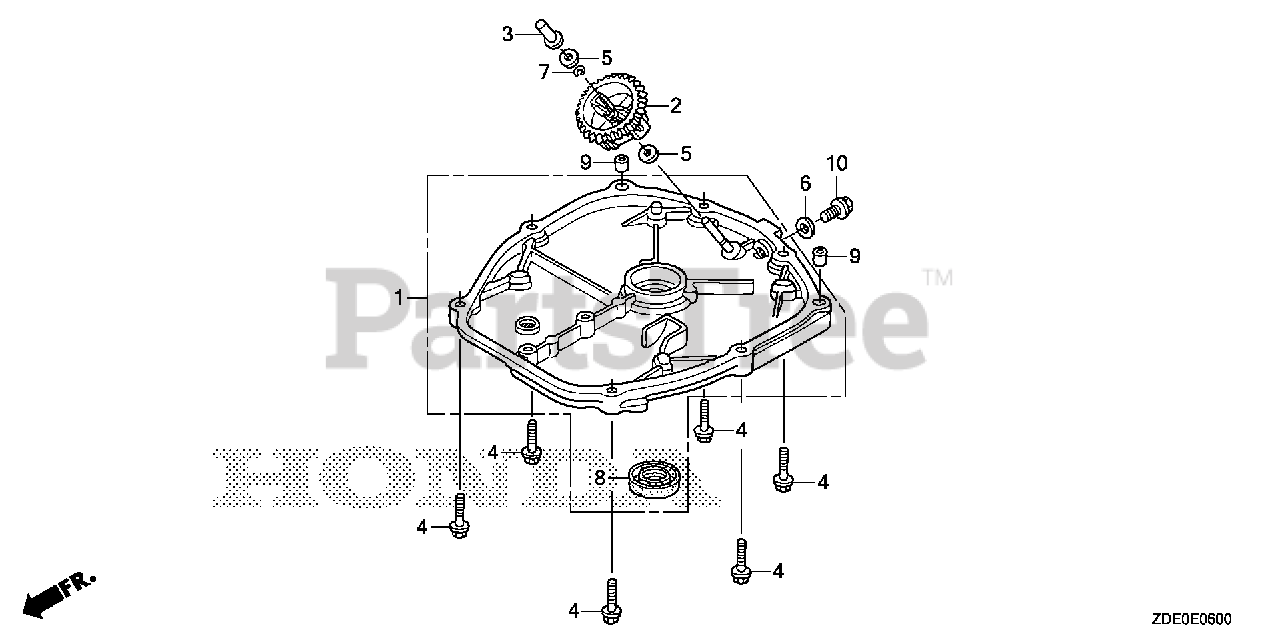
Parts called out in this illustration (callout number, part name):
1	COVER, CRANKCASE SIDE
2	GOVERNOR ASSY.
3	SLIDER, GOVERNOR
4	BOLT, FLANGE (5X23)
5	WASHER (4.2X13)
6	GASKET (8MM)
7	CLIP, GOVERNOR HOLDER
8	OIL SEAL (17X27X5) (KOYO)
9	PIN A, DOWEL (6X10)
10	BOLT, FLANGE (8X12)
